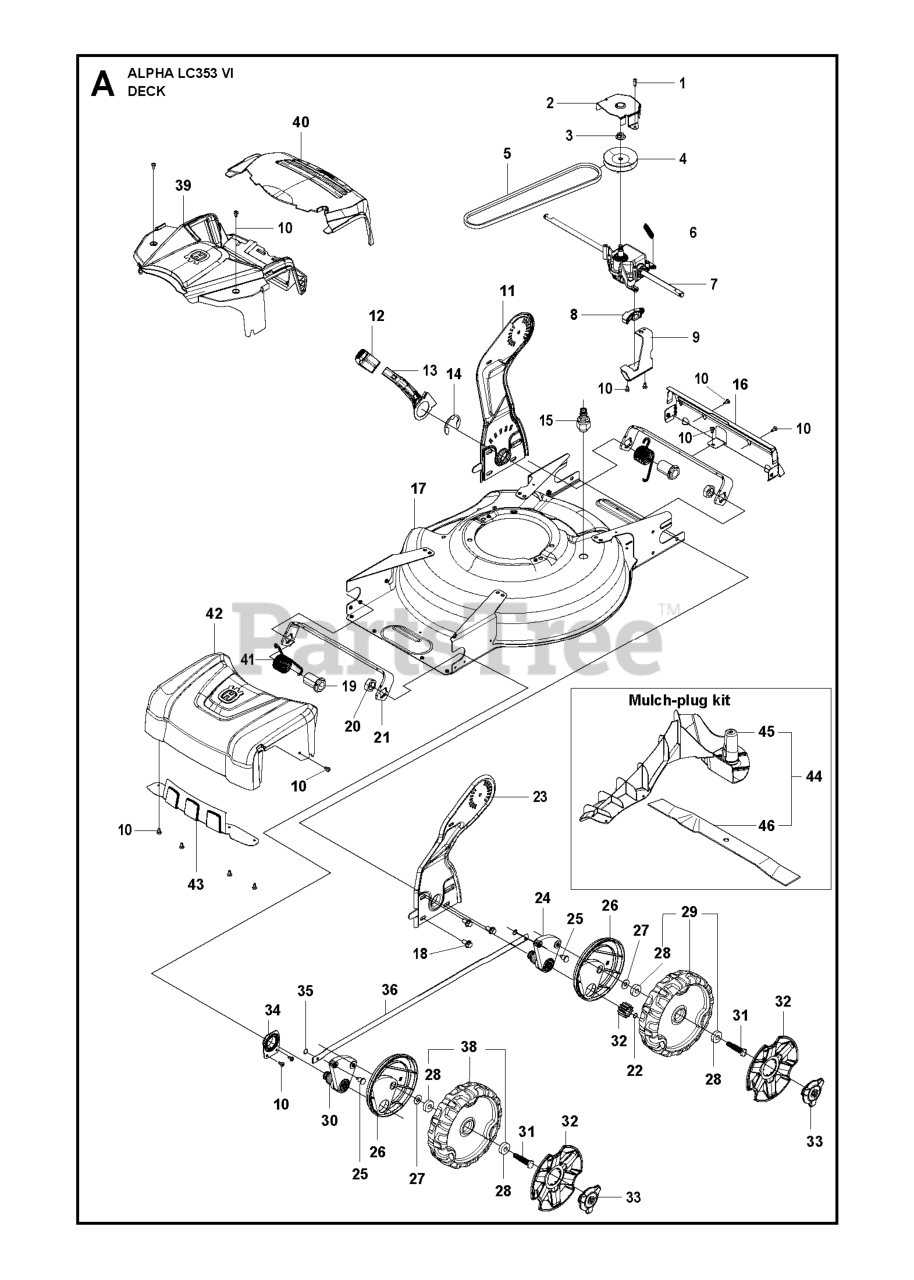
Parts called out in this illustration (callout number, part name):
1	SCREW ITXPANT T50X16 ZN/FE (A
5	BELT WRAPPED V-BELT Z 31 3/4"
10	SCREW ITXPANTT M5X10 ZPB (A00
28	BALL BEARING
35	FASTENER
38	WHEEL ASSY 210, IDLE, MEDIUM
